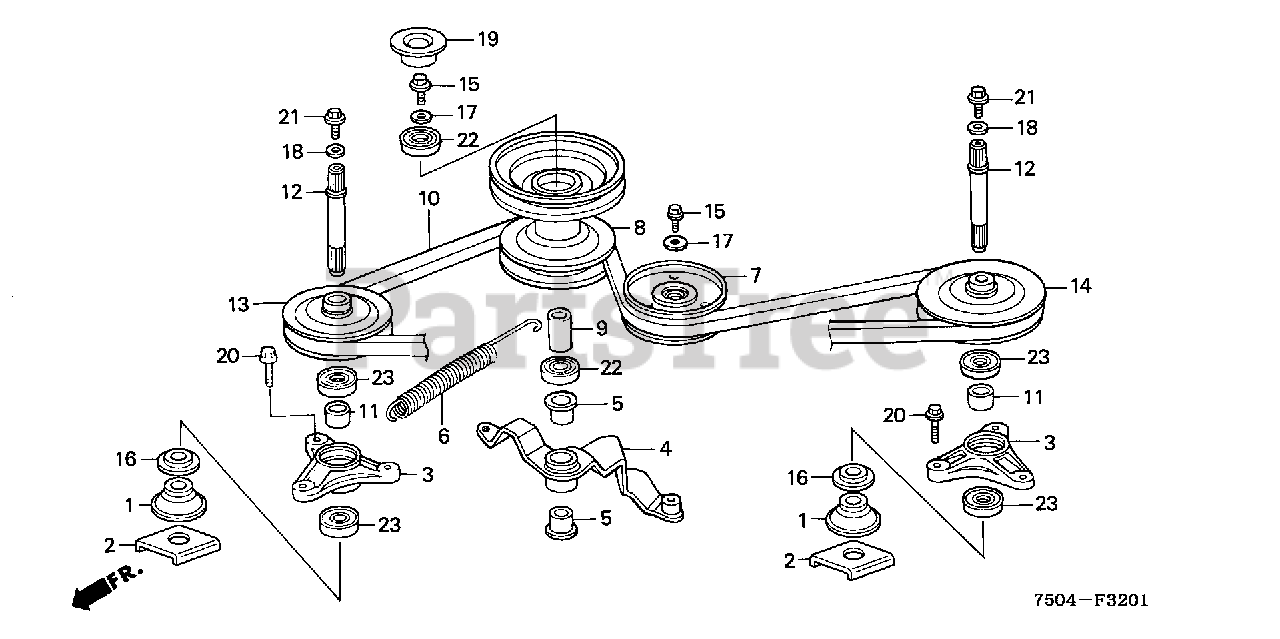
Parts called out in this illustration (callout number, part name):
1	HOLDER, BLADE
2	HOLDER, BLADE (B)
3	HOUSING, BEARING
4	ARM, TENSIONER
5	BUSH, TENSIONER ARM
6	SPRING, TENSIONER ARM
7	ROLLER, TENSIONER
8	PULLEY KIT, DRIVEN
9	COLLAR, DRIVEN PULLEY
10	V-BELT, BLADE (LB-60)
11	COLLAR, BLADE SHAFT
12	SHAFT, BLADE
13	PULLEY, BLADE (115)
14	PULLEY, BLADE (109)
15	BOLT, WHEEL
16	WASHER, BLADE HOLDER
17	WASHER (8MM)
18	WASHER (10.3MM)
20	BOLT, FLANGE (10X28)
21	BOLT, FLANGE (10X16) (NA USE ALT:95700-10016-08)
22	BEARING, RADIAL BALL (6203UU)
23	BEARING, RADIAL BALL (6204UU)
